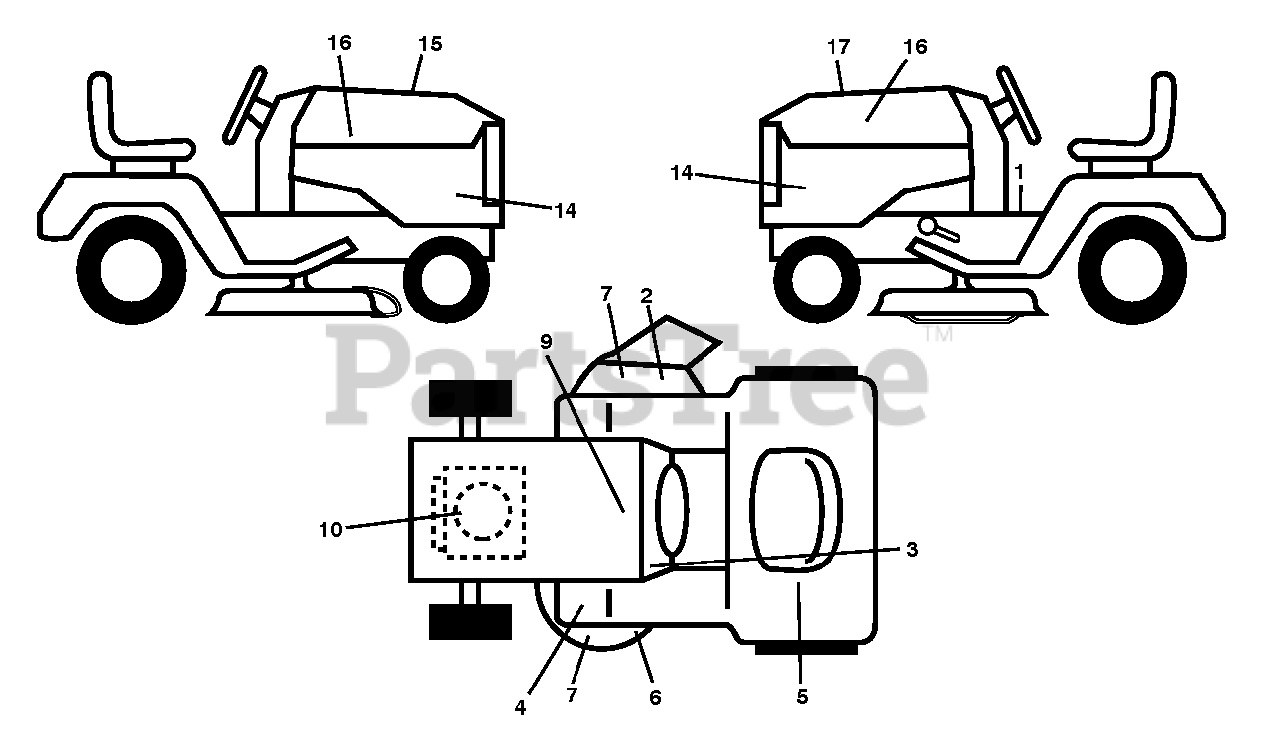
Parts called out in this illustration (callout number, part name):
1	DECAL.WARNING.2007.ENG/FR
2	DECAL.DECK.6MIL./DEF.SHLD.WARN
3	DECAL.SNOWFLAKE.MS498.HUSQ
4	DECAL.PEDAL.HUSQ.CROWN
5	DECAL FUEL SELECTOR
6	DECAL.MOWER.SCH.48/54.PREM
7	DECAL.DECK.6MIL.EURO.NOSTEP
9	DECAL BTRY SYMBOLS
10	DECAL.ENG.BS.ENDUR.27HP.382010
14	DECAL SIDE PANEL
15	DECAL.WARNING.CUST.RESP.E85.
16	DECAL.BADGE.170MM.TEXTLOGO.
17	DECAL.RPL.BSM49.ENDR.TGB.52F
